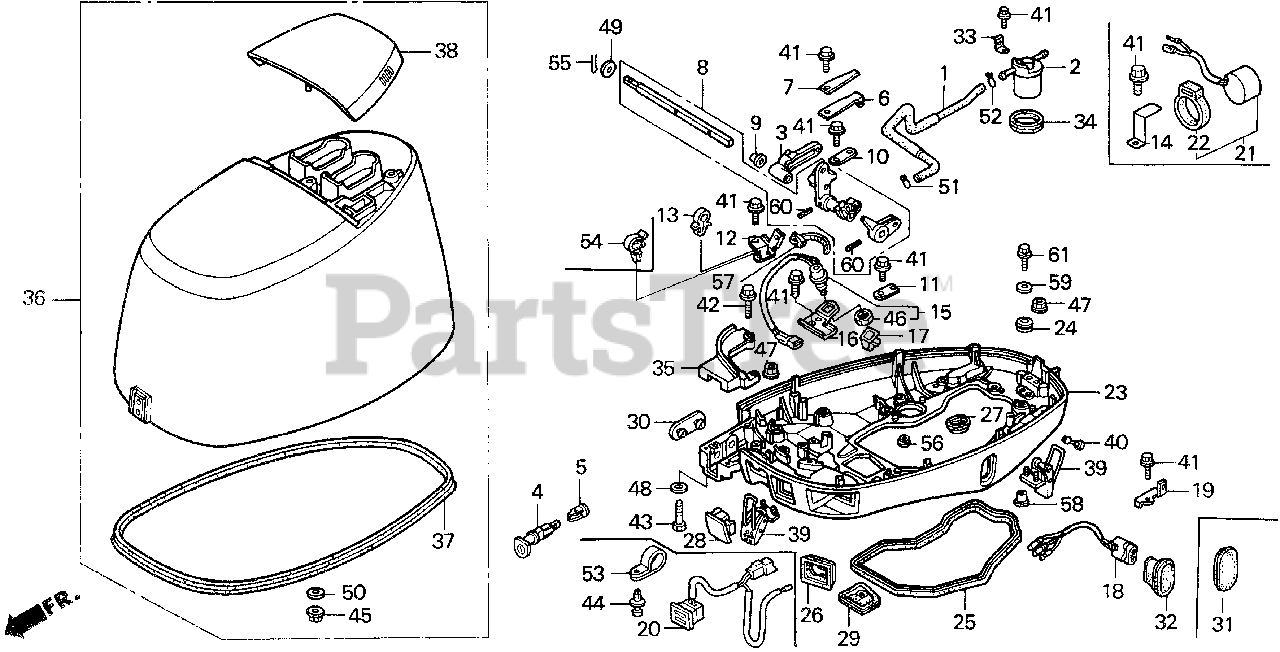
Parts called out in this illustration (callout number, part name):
1	TUBE, FUEL
2	FILTER, FUEL (TOYO ROKI)
3	ARM, THROTTLE
4	KNOB, CHOKE
5	GUIDE, CHOKE KNOB
6	SPRING, CLICK
7	SPRING, CLICK ASSIST
8	SHAFT, SHIFT
9	BUSH, SHAFT
10	PLATE, SHIFT
11	PLATE, SHIFT SHAFT
12	BRACKET, CABLE CLIP (S)
13	CLAMP, WIRE
15	SWITCH ASSY., NEUTRAL
16	BRACKET, NEUTRAL SWITCH
17	PLATE, NEUTRAL SWITCH
18	SWITCH ASSY., POWER TILT
19	STAY, POWER TILT SWITCH
23	CASE, ENGINE (LOWER) *NH282MU* (OYSTER SILVER METALLIC-U)
24	GROMMET, CASE (LOWER)
25	SEAL, CASE (LOWER)
26	GROMMET, CASE (LOWER) (B)
27	GROMMET, CASE (LOWER) (C)
28	GROMMET, CASE (LOWER) (D)
29	GROMMET, CASE (LOWER) (E)
30	GROMMET, CASE (LOWER) (F)
32	GROMMET, CASE (LOWER) (G)
33	RETAINER, FUEL STRAINER
34	GROMMET, FUEL STRAINER
35	CASE, SEPARATE *NH282MU* (OYSTER SILVER METALLIC-U)
36	COVER, ENGINE *NH282MU* (OYSTER SILVER METALLIC-U)
37	SEAL, ENGINE COVER
38	HANDLE, TILT *NH282MU* (OYSTER SILVER METALLIC-U)
39	LEVER, FASTENER
40	GROMMET, WATER CHECK
41	BOLT, FLANGE (6X12)
42	BOLT, FLANGE (6X28)
43	BOLT, HEX. (6X40)
44	SCREW, RIVET (5X10)
45	NUT, U (6MM)
46	NUT, HEX. (20MM)
48	WASHER, PLAIN (6MM)
49	WASHER (7.5MM)
50	WASHER (6MM)
51	CLIP, TUBE (B10)
52	CLIP, TUBE (B12)
53	CLIP (14MM)
55	PIN, SPLIT
55	PIN, SPLIT (2.0)
56	PLUG, CHANGE REINFORCEMENT
57	BAND, WIRE HARNESS (123.5MM) (BLUE)
58	COLLAR, IGNITION CONTROL MODULE CASE
58	COLLAR, MODULE IGNITION CONTROL CASE (CDI)
59	WASHER, PLAIN (6MM)
60	PIN, SPRING (3X20)
61	BOLT, FLANGE (6X28)
